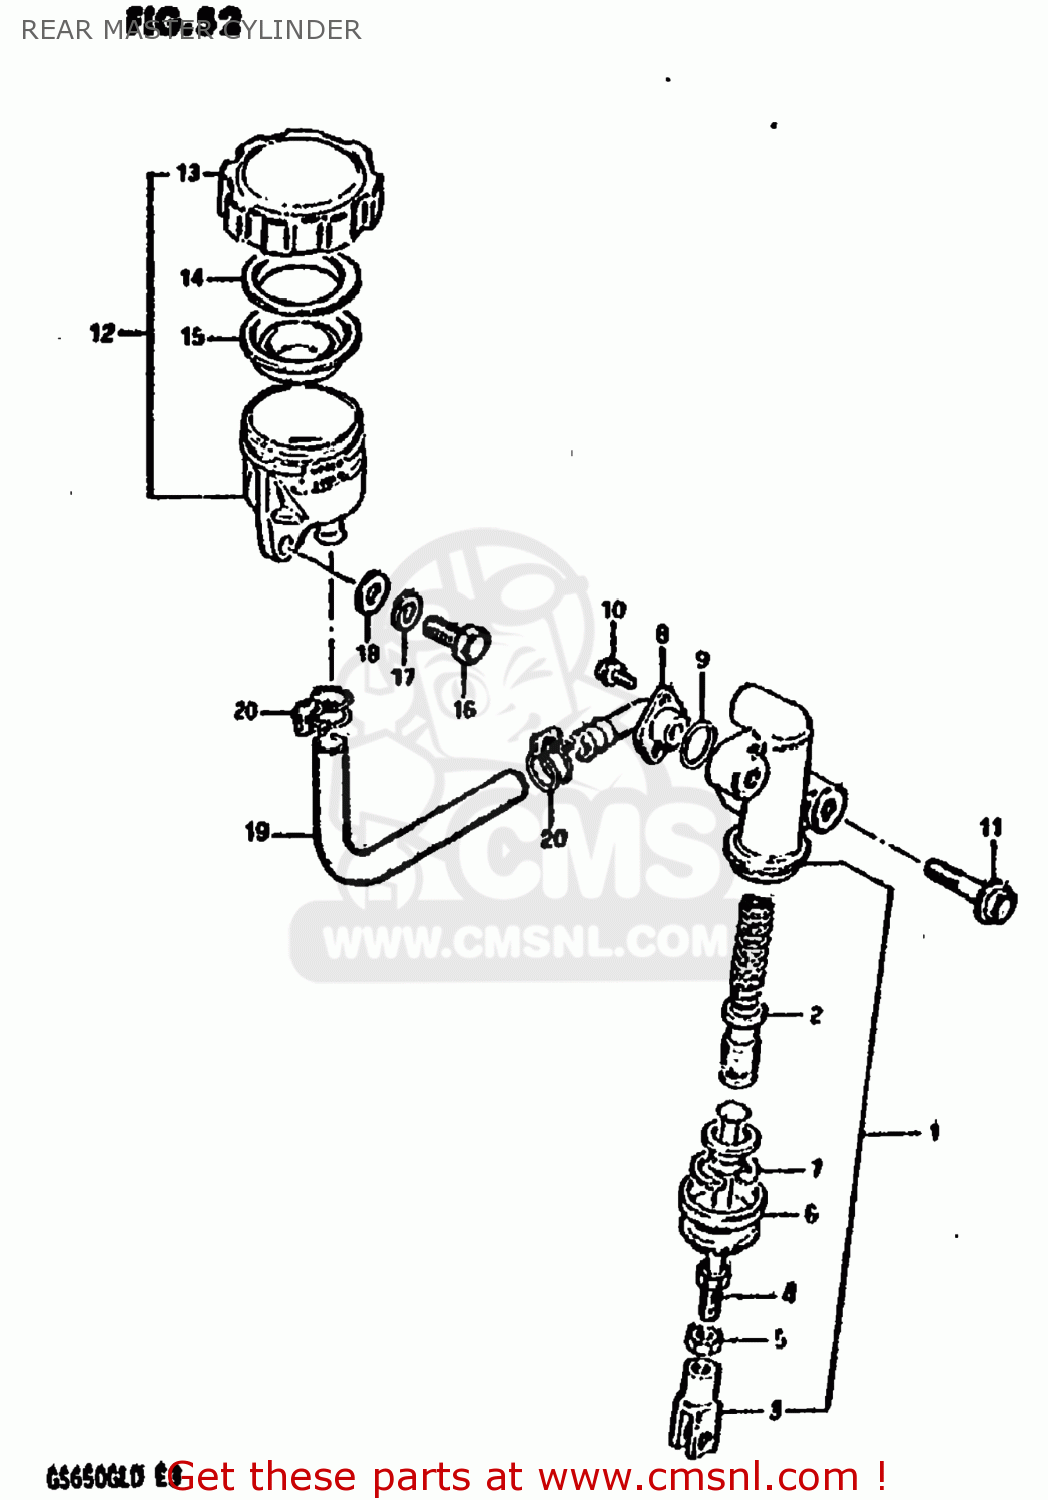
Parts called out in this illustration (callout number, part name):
1	CYLINDER ASSEMBLY,REAR MASTER
2	PISTON/CUP SET
3	YOKE
4	ROD,REAR MASTER CYLINDER
5	NUT,MASTER CYLINDER
6	BOOT
7	CIRCLIP
8	CONNECTOR,HOSE
9	O RING
10	SCREW
11	BOLT
12	TANK ASSEMBLY,RESERVOIR
13	CAP
14	PLATE,DIAPHRAGM
15	DIAPHRAGM
16	BOLT, UPPER
17	LOCK WASHER
18	WASHER
19	HOSE,RESERVOIR TANK
20	CLAMP
